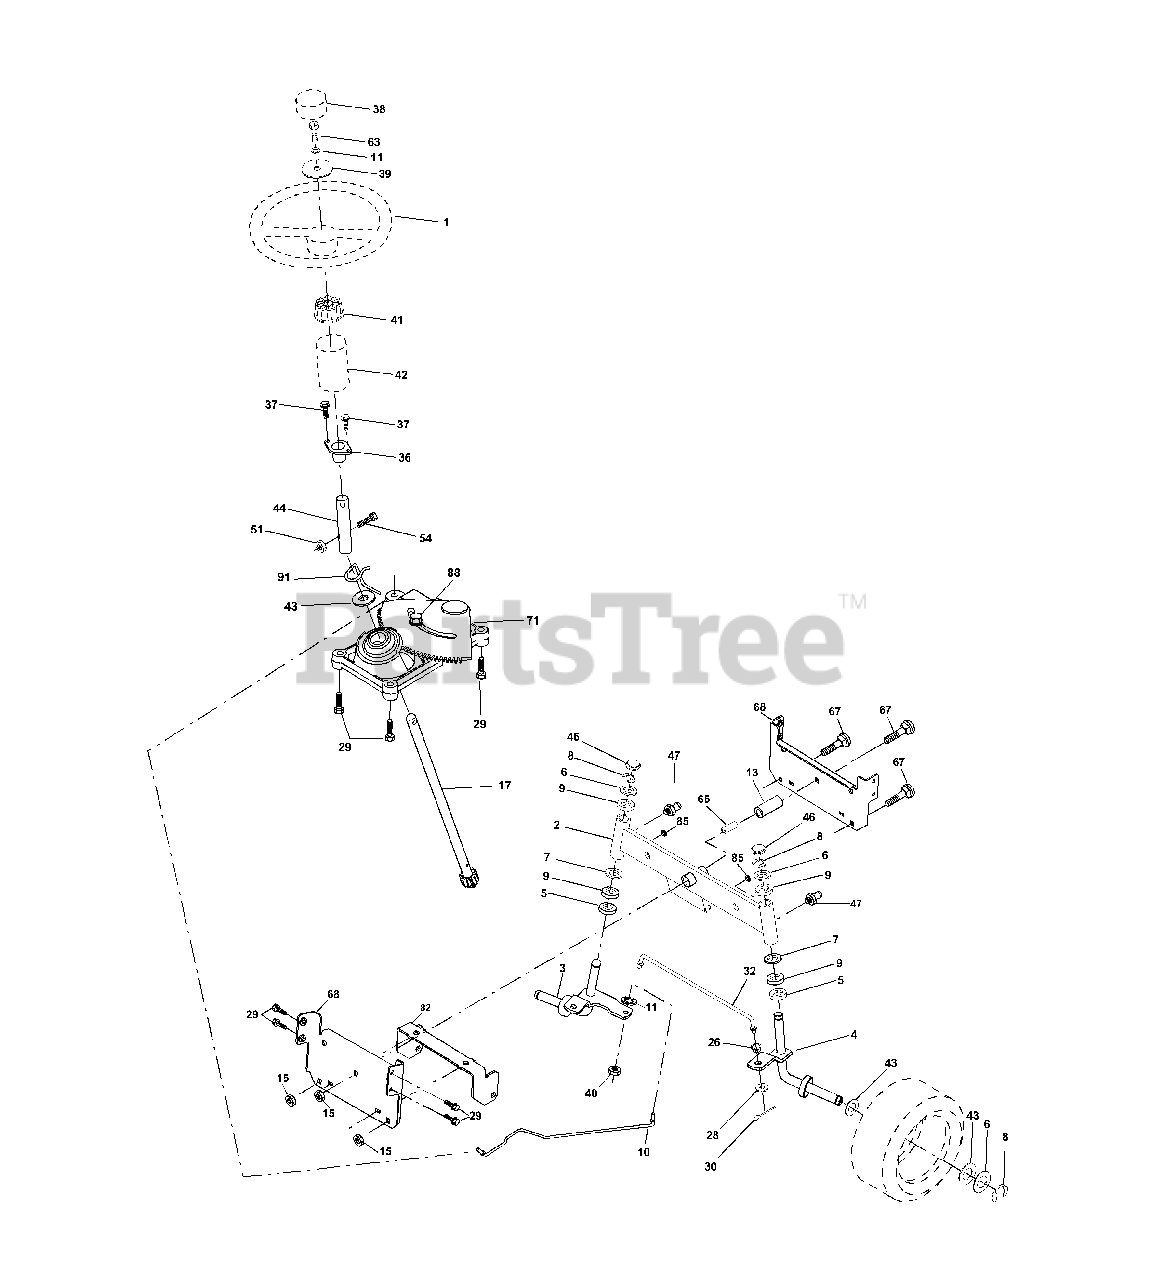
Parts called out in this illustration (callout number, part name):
1	Steering Wheel
2	Axle Assembly STMP Dropped STL
3	Spindle Assembly, L.H.
4	Spindle Assembly, R.H.
5	Bearing, Race, Thrust, Hardened
6	Washer 25/32 x 1-5/8 x 16 Gauge
7	Washer 27/32 x 1-1/4 x 16 Gauge
8	Ring, Klip
9	Bearing, Steering Column
10	Draglink
11	Washer, Lock
13	Spacer Bearing Axle Front
15	Hexflange Lock
17	Shaft Assembly, Steering
26	Bushing, Link, Drag
28	Washer 13/32 x 7/8 x 16 Gauge
29	Screw, 3/8-16 x 3/4
30	Pin
32	Rod, Tie
36	Bushing, Steering
37	Screw
38	Cap, Steering Wheel
39	Washer 13/32 x 2-3/8 x 12 Gauge
40	Gripco Nut
41	Adaptor, Steering Wheel
42	Boot, Steering
43	Washer 25/32 x 1-1/4 x 16 Gauge
44	Shaft Extension Steering
46	Cap, Spindle
47	Fitting, Grease
51	Nut lock Hex w/Ins 5/16-18
54	Bolt Fin Hex 5/16-18 UNC x 1-1/4
63	Bolt Fin Hex 3/8-16 x 1-1/4
65	Spacer Brace Axle
67	Bolt, Rdhd Sq 3/8-16 UNC x 2-1/4
68	Axle, Brace
71	Steering Asm
82	Bracket Susp Chassis Front
85	Fastener Christmas Tree
88	Shoulder Bolt
91	Clip Steering
